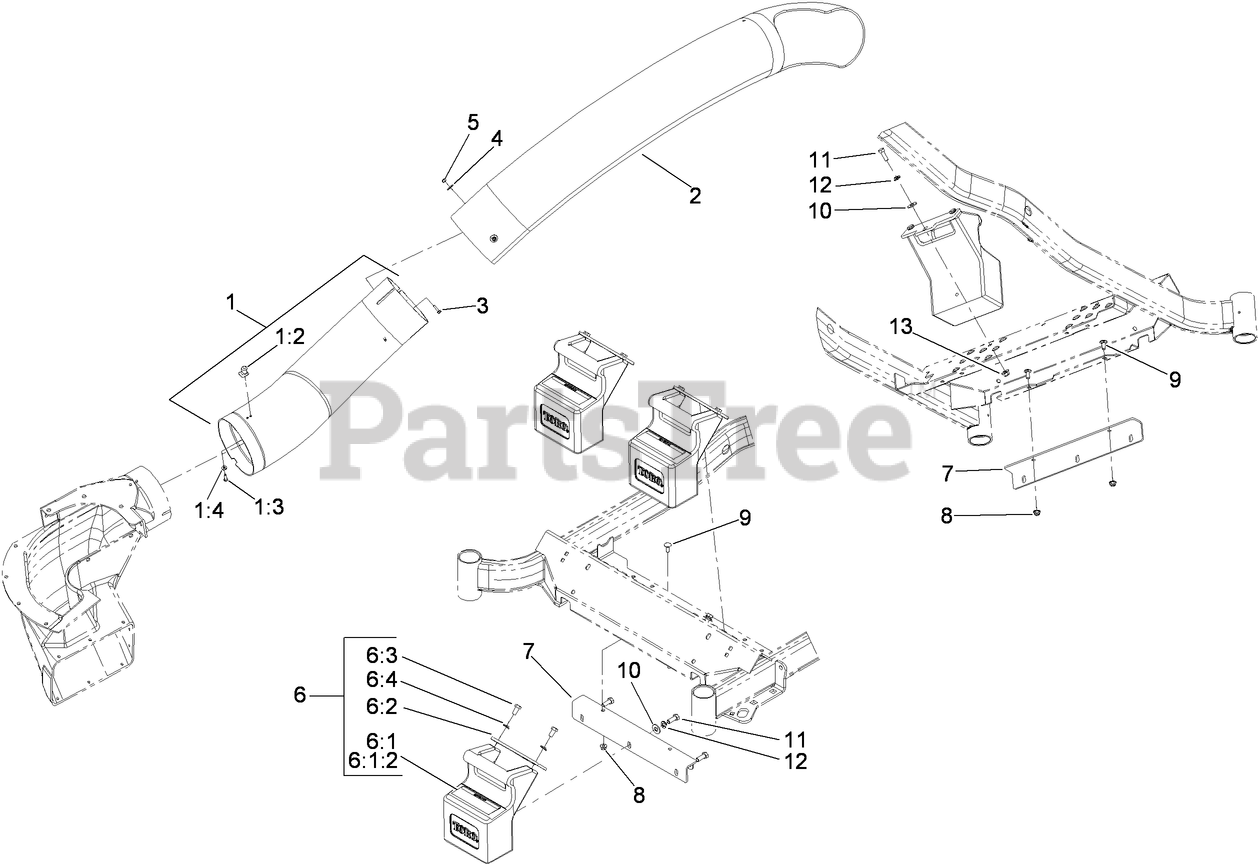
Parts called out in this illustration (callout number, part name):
1	LOWER TUBE ASM
1:2	LATCH-KEEPER
1:3	SCREW-PPH
1:4	WASHER-FLAT
2	TUBE-UPPER
3	SCREW-HWH
4	WASHER-FLAT
5	NUT-LOCK, NI
6:1:2	DECAL-WARNING, COUNTERWEIGHT
6:2	TAB-SUPPORT, WEIGHT
6:3	SCREW-HH
6:4	WASHER-LOCK
7	BRACKET-MOUNT, WEIGHT
8	NUT-HF, NI
9	SCREW-CARR
10	WASHER-FLAT
11	SCREW-HH
12	WASHER-LOCK
13	NUT-HF, NI
